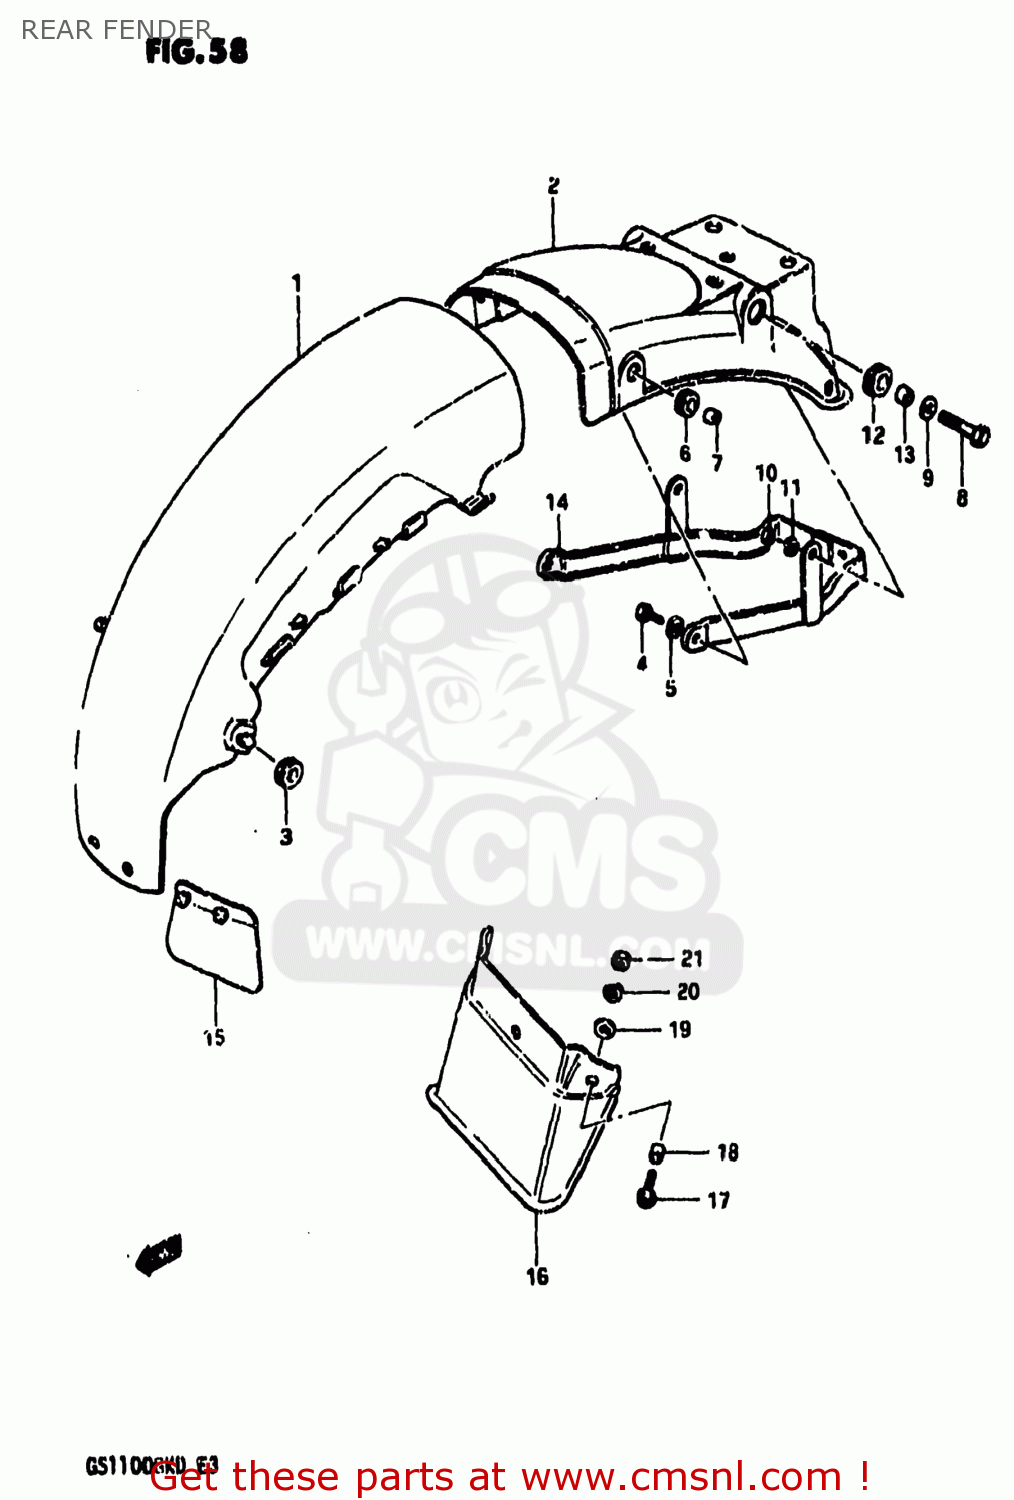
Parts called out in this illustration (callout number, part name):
1	FENDER,REAR
2	FENDER,REAR
3	CUSHION
4	BOLT, UPPER
5	LOCK WASHER
6	CUSHION
7	WASHER
8	BOLT 8X40
9	WASHER
10	NUT
11	LOCK WASHER
12	CUSHION
13	SPACER (8.2X12X7.5)
14	REINFORCEMENT,REAR FENDER
15	GUIDE,RR FENDER MUD
16	EXTENSION,REAR FENDER
17	SCREW (6X15)
18	SPACER(6.2X8.3X5.7)
19	WASHER(6.5X18X1)
20	LOCK WASHER
21	NUT
